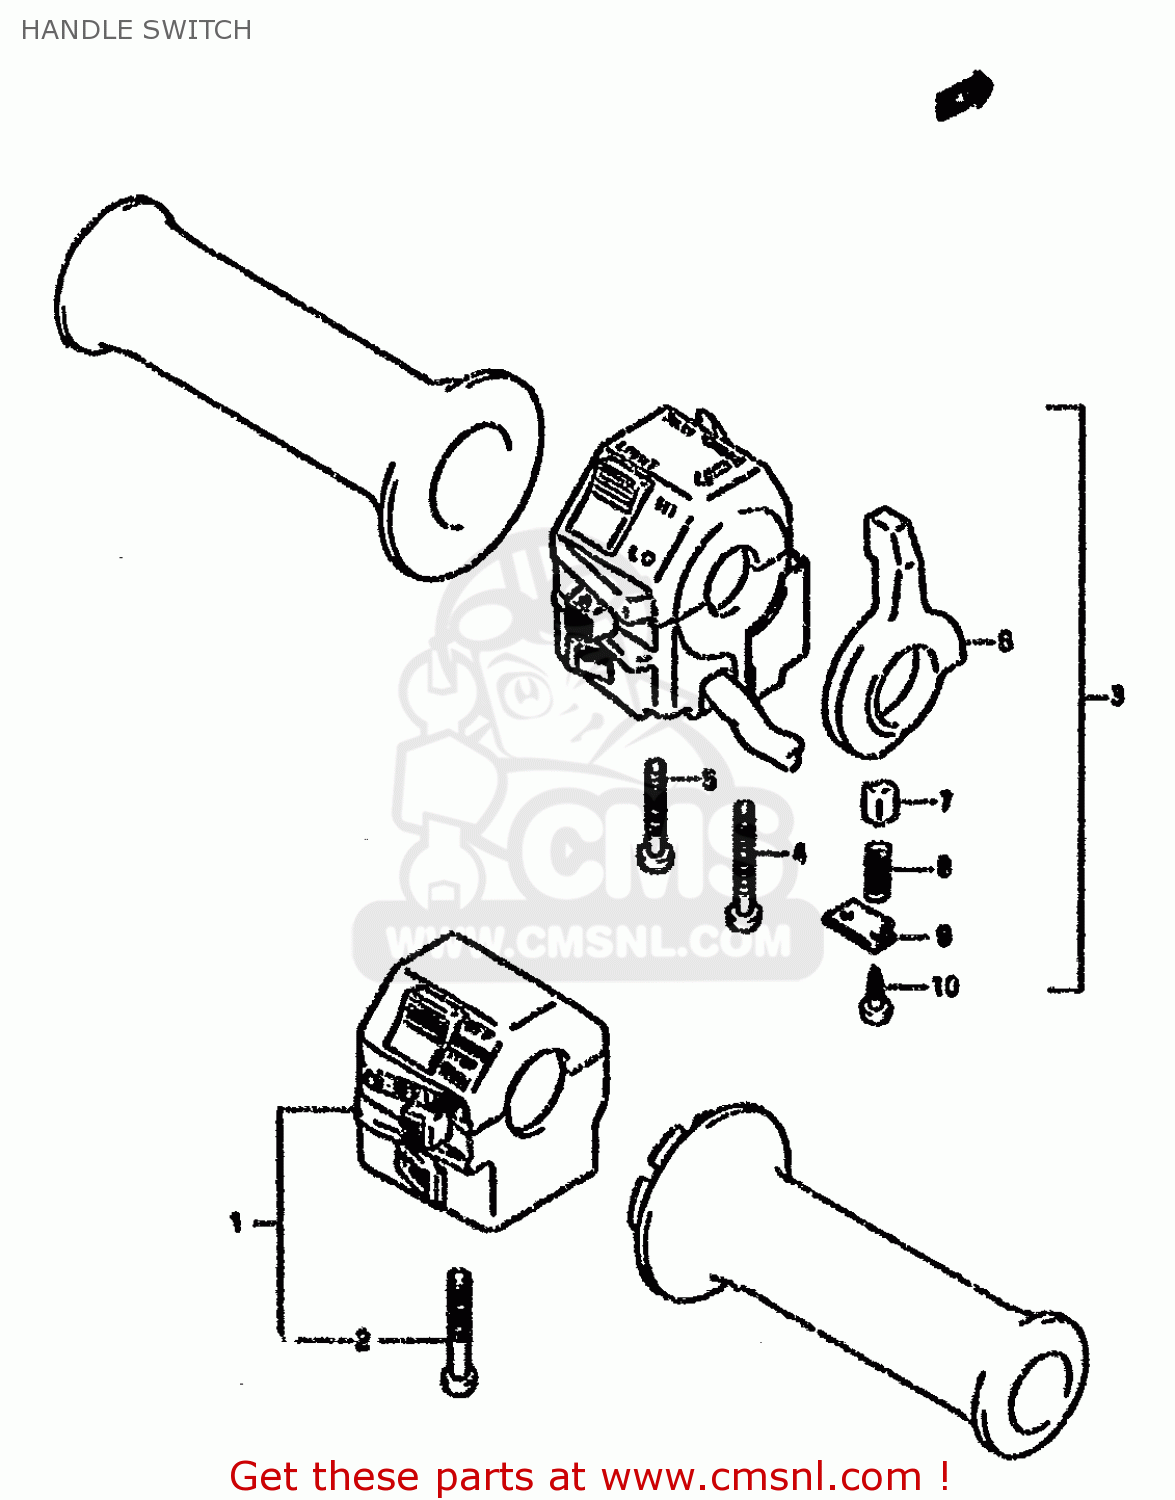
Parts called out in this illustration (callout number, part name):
1	SWITCH ASSY,R
2	SCREW, 5X45
3	SWITCH ASSY
4	SCREW, 5X45
5	SCREW
6	LEVER,CHOKE
7	PIECE,SLIDE
8	SPRING
9	PLATE
10	SCREW, TRUNK BOX
